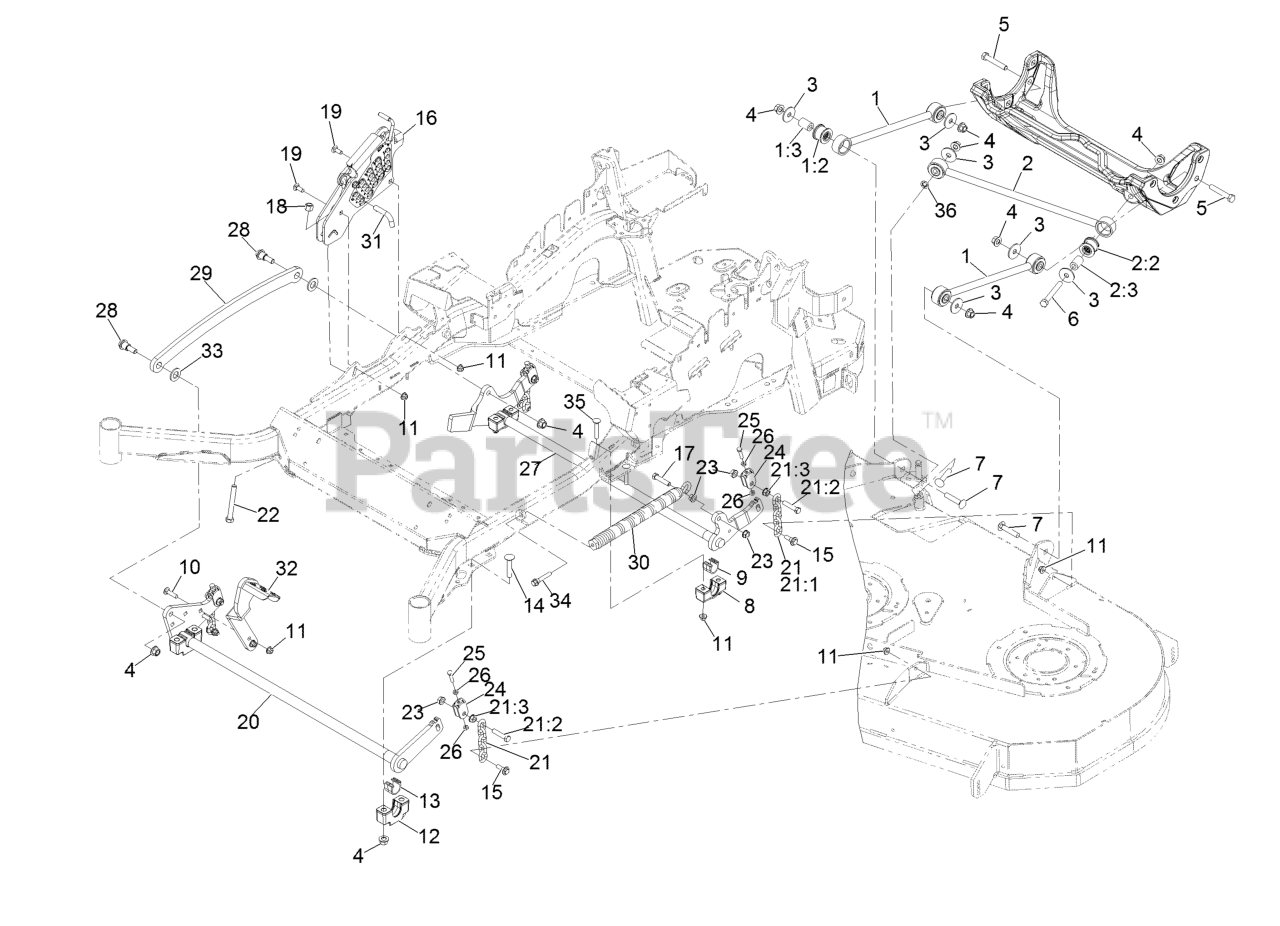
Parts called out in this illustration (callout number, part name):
1	DECK STRUT ASM
1:2	BUSHING-SUSPENSION, RUBBER
2	PANHARD ROD ASM
2:2	BUSHING-SUSPENSION, RUBBER
3	WASHER-THRUST
4	Nut-Lock 1/2-13
5	SCREW-HH
6	SCREW-HH
7	SCREW-CARR
8	SUPPORT-CROSS SHAFT, BEARING REAR
9	BEARING-CROSS SHAFT, REAR
10	SCREW-CARR
11	NUT-HF, NI
12	SUPPORT-CROSS SHAFT, BEARING
13	BEARING-CROSS SHAFT, FRON
14	Bolt-Carriage 1/2-13 X 2 1/2 Spl Neck
15	SCREW-SHOULDER, HHF
16	HOC ASM
17	SCREW-HH
18	NUT-LOCK, NI
19	BOLT-CARR
20	DECKLIFT-FRONT
21	DECK LIFT CHAIN ASM
21:1	CHAIN-LIFT, DECK
21:2	SCREW-HH
22	BOLT-TAP
24	YOKE-ADJUST, DECK
25	SCREW-HH
26	NUT-JAM
27	LIFT-DECK, REAR
28	SCREW-SHOULDER, HHF 1/2-13 X 1.12
29	LINK-LIFT, DECK
30	SPRING-EXTENSION
31	PIN-HOC
32	LEVER-FOOT
33	WASHER-FLAT
34	BOLT-SHOULDER
35	Bolt-Carriage 3/8-16 X 2 1/4
36	NUT-PUSH
